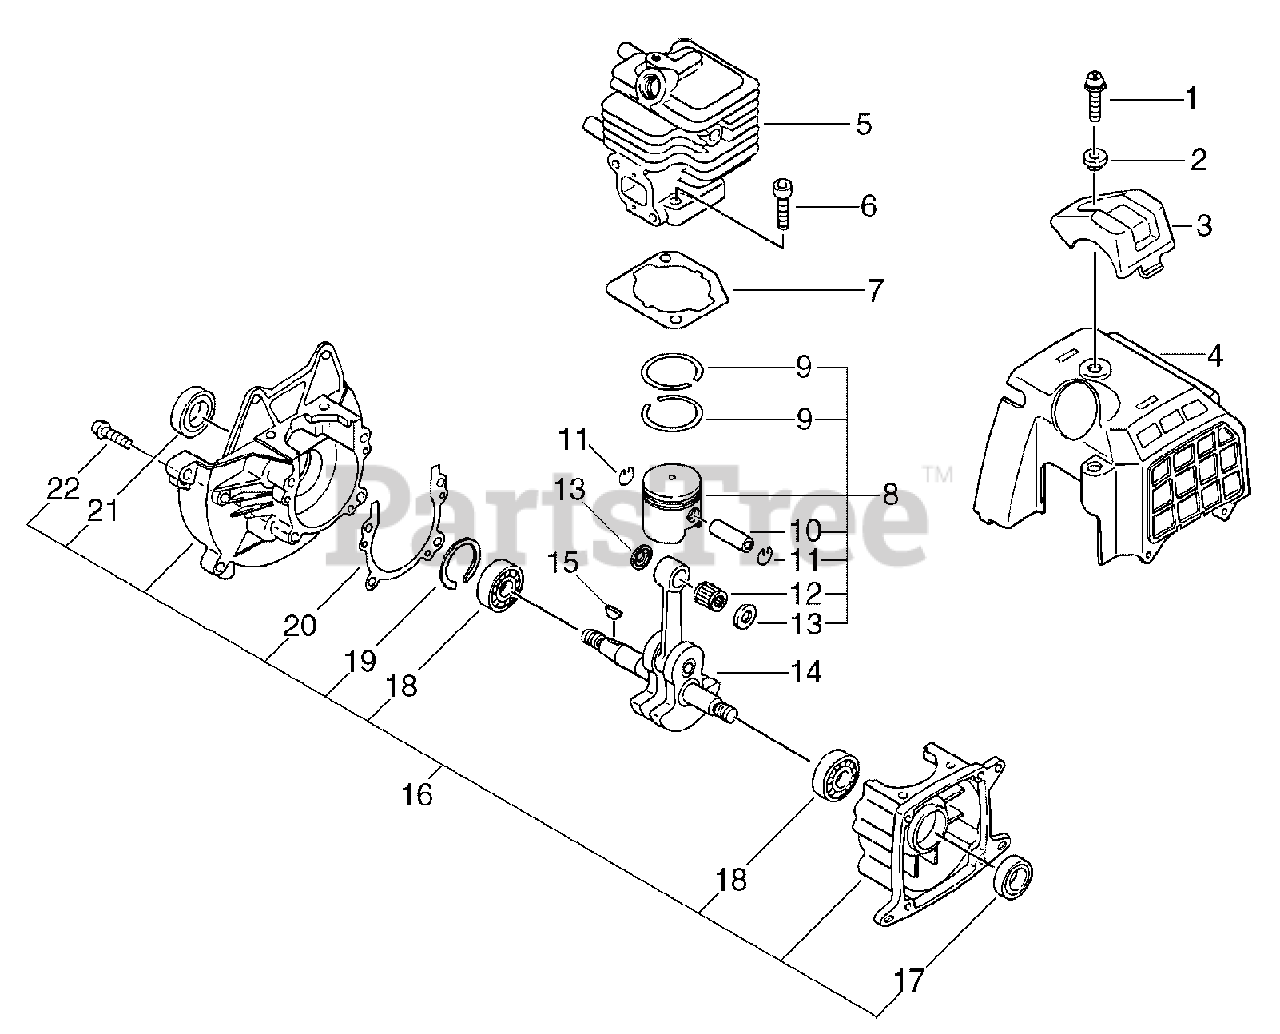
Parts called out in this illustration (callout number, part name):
1	BOLT, FLANGE
2	COLLAR 5
3	GUARD, TOP
4	COVER, ENGINE
5	CYLINDER
6	BOLT 5×22
7	GASKET, CYLINDER
8	PISTON KIT
9	RING, PISTON
10	PIN, PISTON
11	RING, SNAP
12	BEARING, NEEDLE 8
13	WASHER, THRUST
14	CRANKSHAFT ASSY
15	KEY, WOODRUFF
16	CRANKCASE KIT
17	SEAL, OIL 12
18	BEARING, BALL 6001
19	RING, SNAP 28
20	GASKET, CRANKCASE
21	SEAL, OIL 12
22	BOLT 5×25
